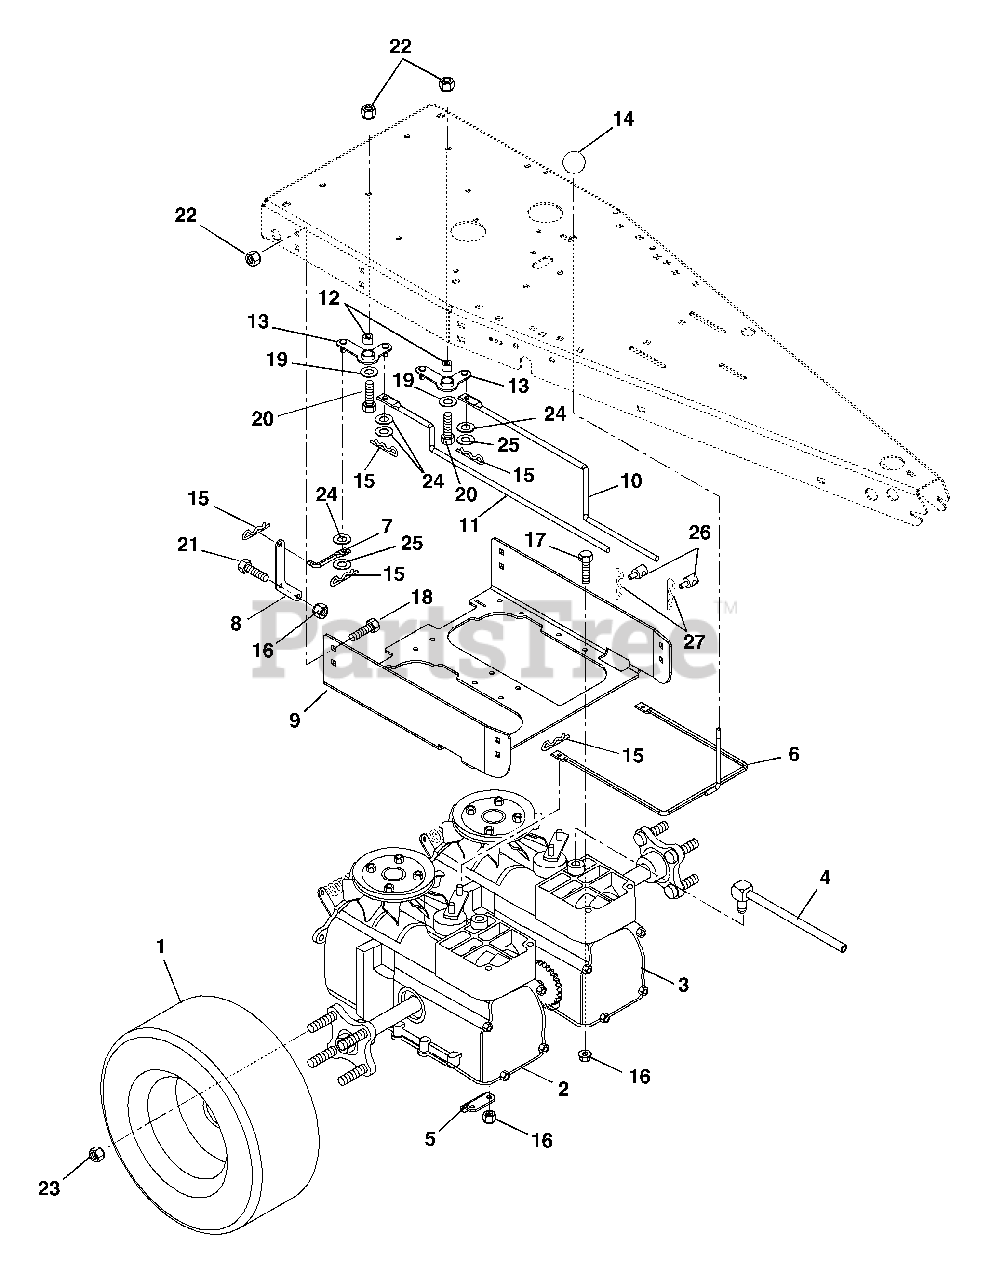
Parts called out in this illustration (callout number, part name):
1	T/WHL ASM 18X6.50-8 2 PLY
2	TRANSAXLE, HYDRO-GEAR
3	TRANSAXLE, HYDRO-GEAR
4	IZT, BREATHER ASSEMBLY
5	BRACKET-AXLE SUPPORT
6	DUMP ROD WLDM'T
7	ROD-BELL CRANK
8	BRACKET
9	CRADLE, IZT
10	ROD-STEERING LH
11	ROD-STEERING RH
12	BSHG-SLV .391X.688X.52 PM
13	WLDM'T-BELL CRANK
14	KNOB, BALL 5/16-18 X 1.5
15	PIN-HAIR, ENDRIES #25 YWZC
16	NUT-LK-TOP-FLG .31-18 BLKZC
17	@BLT-HEX .31-18X2.50 GR5 YWZC
18	BLT-RDHDSQNK .38-16X.75 G5BZ
19	@WSHR-FL-STL.38X.875X.083 YWZC
20	@BLT-HEX .38-16X1.25 GR5 YWZC
21	@BLT-HEX .31-18X.75 GR5 YWZC
22	NUT-LK-TOP-FLG .38-16 BLKZC
23	NUT-LUG .50-20 YWZC
24	WSHR-FL-STL .328X.87X.179 YWZC
25	WSHR-FL-STL .390X.75X.125 YWZC
26	TRUNNION, BRAKE .31-18 UNC
27	PIN-HAIR, ENDRIES #25 YWZC
